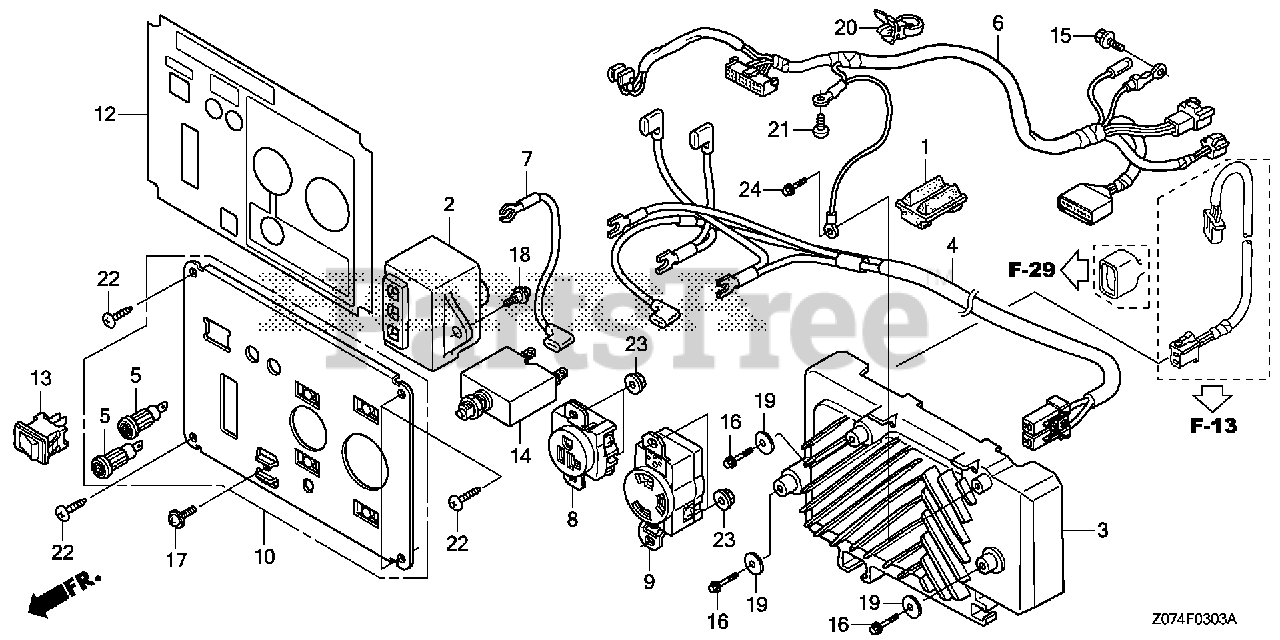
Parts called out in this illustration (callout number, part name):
1	RUBBER B, TANK MOUNTING
2	SPARK UNIT
3	INVERTER UNIT
4	SUB-WIRE HARNESS ASSY.
5	SOCKET, COMPOSITE
6	WIRE HARNESS ASSY., CONTROL
7	WIRE, TERMINAL
8	RECEPTACLE (20A/125V)
9	RECEPTACLE (30A/125V)
10	PANEL, CONTROL
11	PANEL, CONTROL
12	MARK, CONTROL PANEL
13	SWITCH, AUTO-THROTTLE
14	PROTECTOR, CIRCUIT (20A) (WHITE)(TYCO)
15	BOLT, FLANGE (5X10)
16	BOLT, FLANGE (5X12)
17	SCREW, PAN (5X12)
18	SCREW, PAN (5X13)
19	WASHER, PLAIN (20MM)
20	BAND (100MM) (BLACK)
21	SCREW, PAN (5X8)
22	SCREW, TAPPING (5X16) (PO)
23	NUT, FLANGE (4MM)
24	BOLT, FLANGE (5X10)
